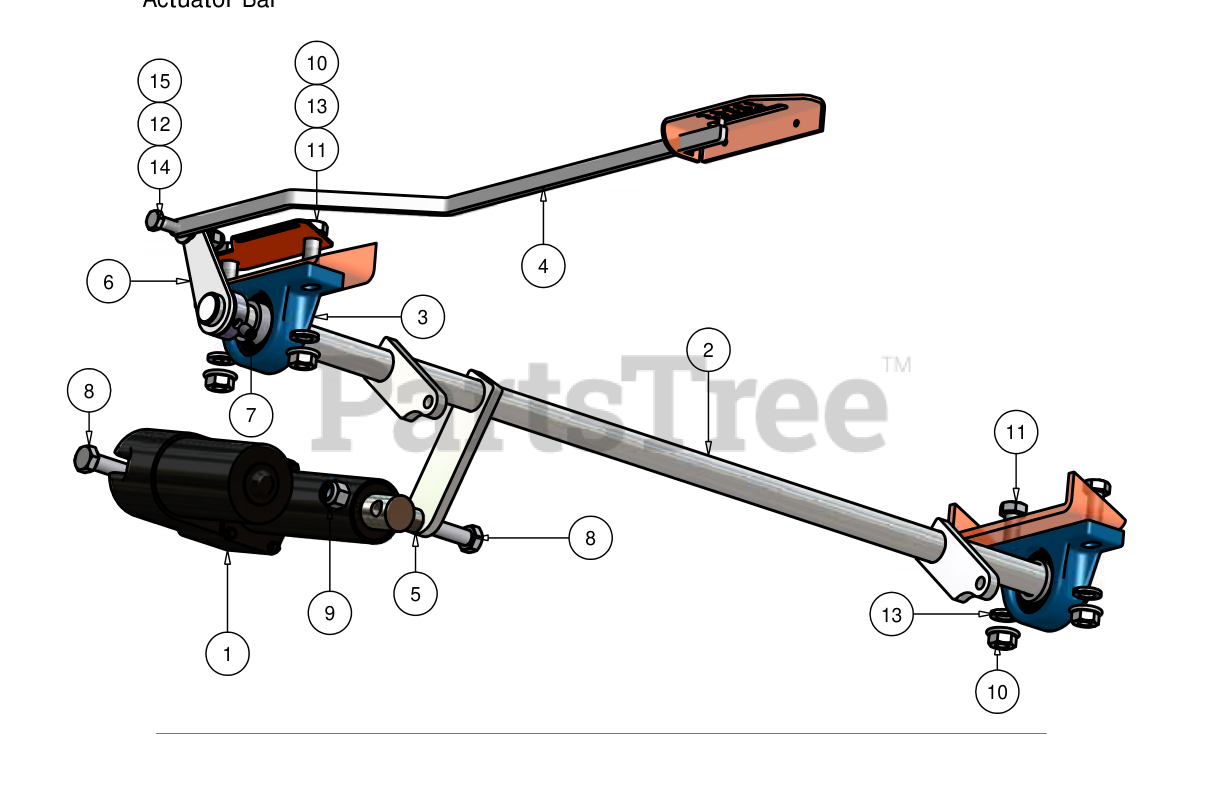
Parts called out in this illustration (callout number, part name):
2	Actuator Bar
3	1" Pillow Block
4	Height Indicator
5	1/2" x 1/2" Collar Spacer
6	2006 Height Indicator Lever
7	3/8" Set Screw
8	1/2" x 3" Hex Bolt
9	1/2" Nylock Nut
10	1/2" Flange Nut
11	1/2" x 1 1/2" Hex Bolt
12	.360 ID Plastic Washer
13	1/2" Lock Washer
14	3/8" x 1" Hex Bolt
15	3/8" Nylock Nut
